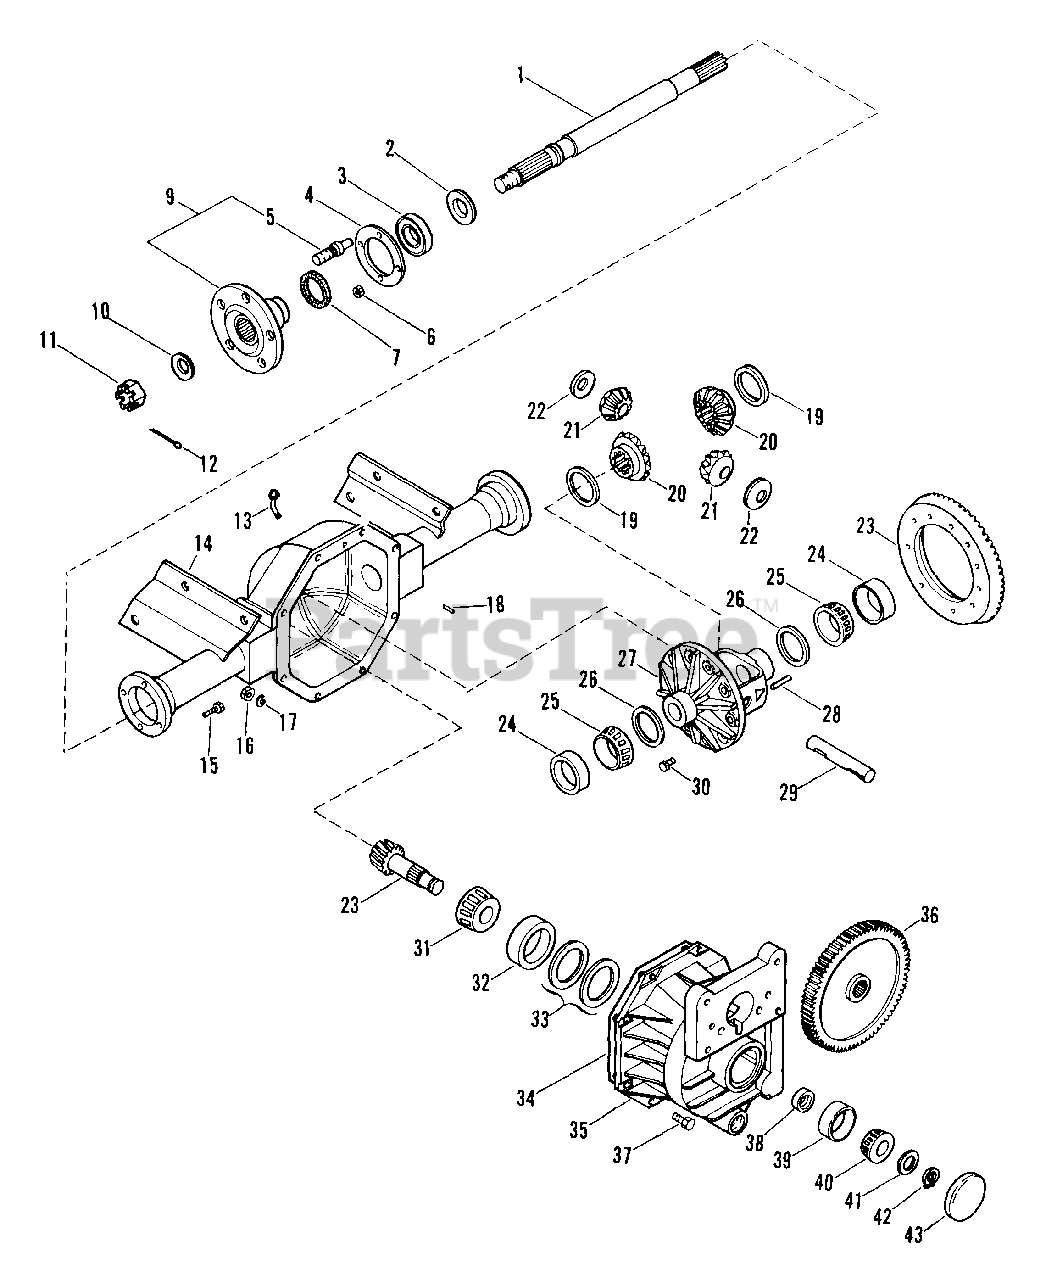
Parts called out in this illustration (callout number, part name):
1	AXLE SHAFT LH
1	AXLE SHAFT RH
1	AXLE SHAFT L H
1	AXLE SHAFT R H
2	SEAL 1.183X1.183X.265
3	BRG-CONE 46MMX17MM
4	GASKET-SEE LETTER L-307
5	CARRIER LUG BOLT
6	NUT-LK-FLG .312-24 GR C
7	FELT SEAL
9	AXLE FLANGE ASSEMBLY
10	WSHR-FL-STL .875X1.500X.1196
11	NUT-SL .875-14
12	PIN-COTR .15X1.50
14	LOWER HOUSING
15	BLT-HEX .31-24X1.25 GR8
16	NUT-HEX .312-18
17	WSHR-LK-INT .313X.030 PL
18	DOWEL PIN
19	WSHR-FL-STL 1.578X2.375X.031
20	Side Gear
20	SIDE GEAR
21	BEVEL GEAR
22	WSHR-BLVL .703X1.593X.031
23	RING & PINION GEAR SET
23	PINION & GEAR
24	BRG-CUP 2.892X.580
25	BRG-CONE 1.63X.78
27	DIFFERENTIAL CASE
28	LOCK PIN
29	PINION SHAFT
30	BLT .38-24X.812 DANA
31	BRG-CONE 1.03X1.0013
31	BRG-CONE 1.188X.84
32	BRG-CUP 2.615X.750
32	BRG-CUP 2.532X.656
33	SHIM
34	GASKET
35	FRONT HOUSING W/BEARING CAP &
35	FRONT HOUSING W/BRG CAP & SCRE
36	SPUR GEAR
37	BLT-HEX .31-18X1.00 PL GR5
38	FRONT PINION BEARING SPACER
39	BRG-CUP 1.968X.550
40	BRG-CONE .875X.72
40	BRG-CONE .844X.72
41	SHIM PACK ASSEMBLY
41	SHIM ASSEMBLY
41	SHIM
42	RG-RTNG-EXT .813X.042
42	RG-RTNG-EXT .875X.042
43	CUP PLUG
